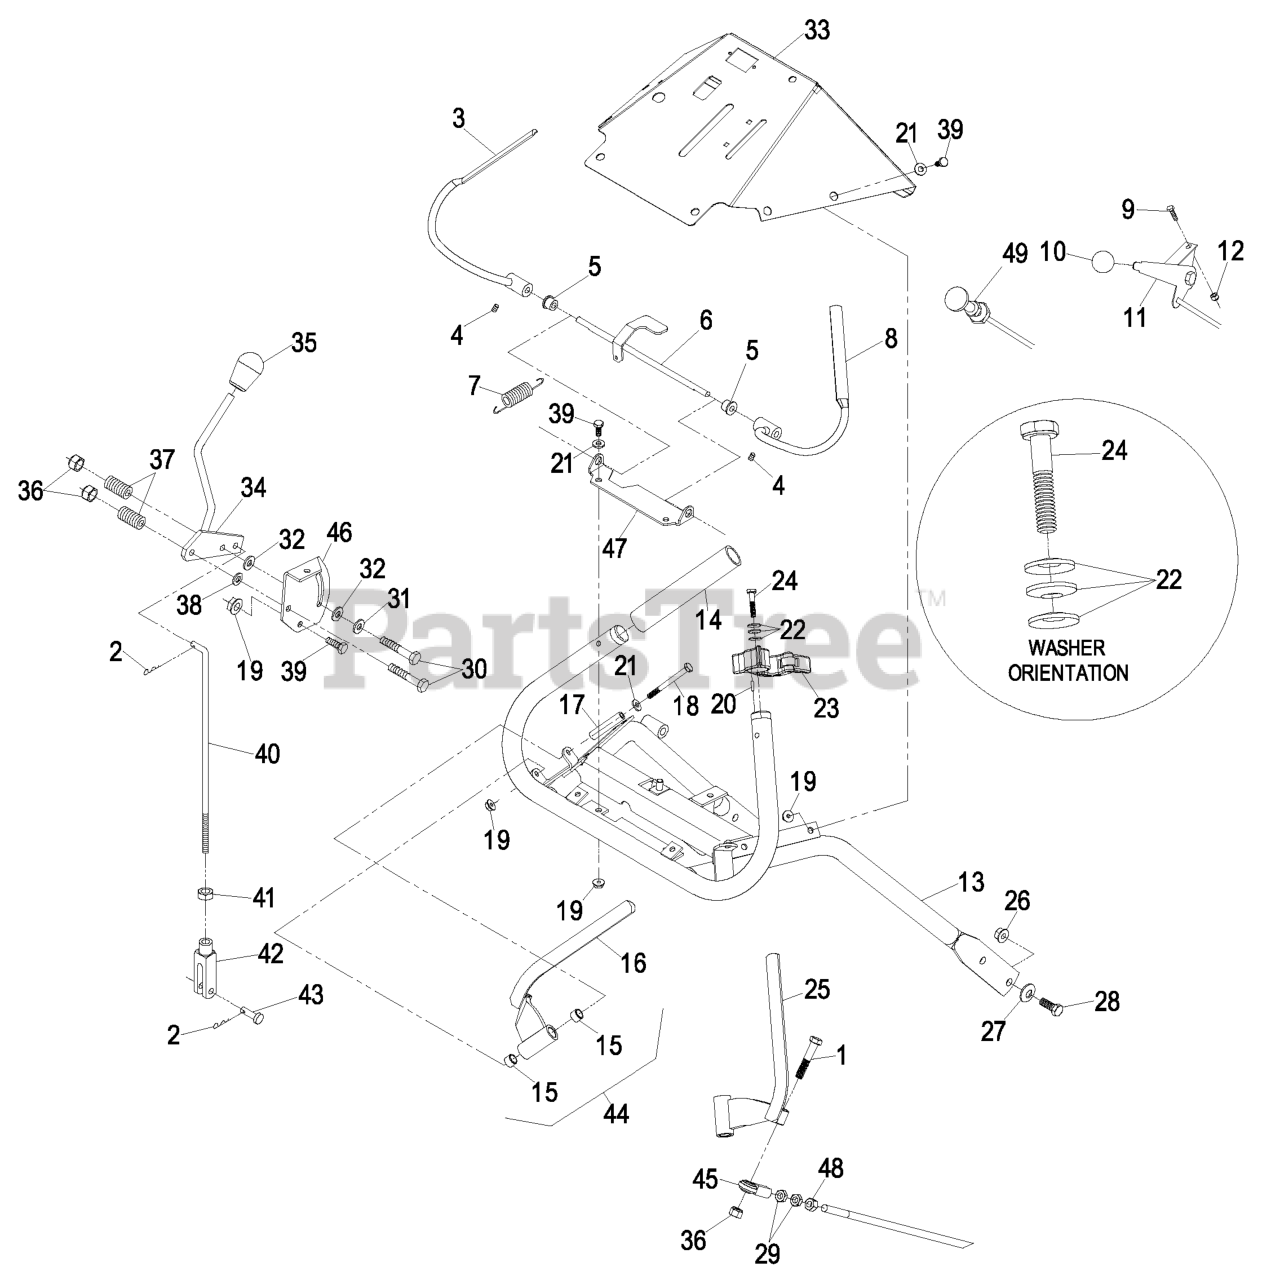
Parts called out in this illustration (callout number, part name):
1	SCREW-HH
2	PIN-COTTER
4	SCREW-SET
5	BUSHING-NYLON
6	WLD,OPC LEVER AXLE
7	SPRING-EXTENSION
9	BOLT-CARR
10	KNOB-BALL
11	THROTTLE CABLE ASM
12	NUT-LOCK, NI
13	WLD,TTH ECS HANDLE
14	GRIP-BAR, HANDLE
15	BUSHING-SLEEVE
17	BUSHING-LEVER, DRIVE
18	SCREW-HH
21	WASHER-FLAT
22	WASHER-SPRING
23	ASM,LATCH RH THUMB
24	SCREW-HH
26	NUT-HHF, WHIZ
27	WASHER-BELLEVILLE
28	SCREW-HH
29	NUT-HJ
30	SCREW-HH
31	WASHER-FRICTION
32	WASHER-FRICTION
33	KIT,TT ECS CONSOLE
35	KNOB, FE.LCKG. BLACK
36	NUT-LOCK, NI
37	SPRING-COMPRESSION
38	WASHER-PLAIN
39	SCREW-HH
40	ROD,SPEED CONTROL
41	NUT-JAM
42	YOKE-ADJUSTABLE
43	PIN-CLEVIS
44	DRIVE LEVER-ASM, RH
45	JOINT-BALL, END
46	BRACKET,SHIFTER SLIDE (PL
47	BRACKET,OPC AXLE
48	NUT-HEX
49	CONTROL-CHOKE
